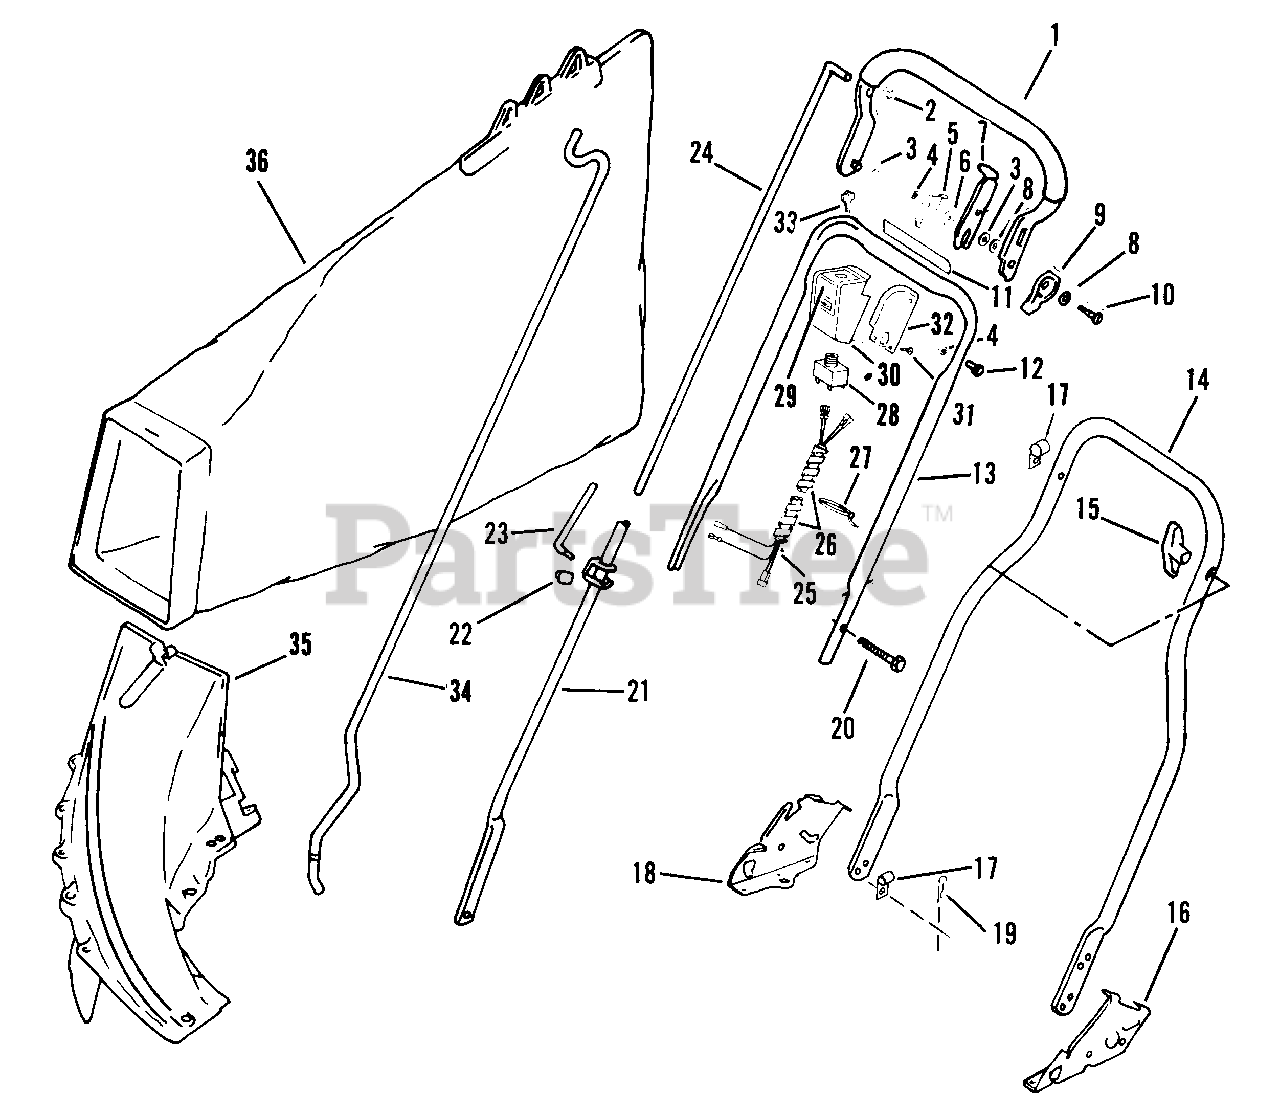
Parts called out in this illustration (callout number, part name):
1	Handle & Grip Assembly
2	Nut
3	Washer
4	Nut-Lock
5	Stop-Handle
6	Washer
7	Lever-Lockout
8	Washer
9	Guard-Lever
10	Bolt-Shoulder
11	Decal
12	Screw-Stop
13	Handle-Center
14	Handle Section-Bottom
15	Knob
16	Bracket-Handle L.H.
17	Clamp
18	Bracket-Handle R.H.
19	Hair Pin
20	Screw Bolt
21	Control Lever Assembly
22	Nut
23	Screw
24	Control Rod
25	Wire Harness Assembly Switch
26	Spiral Tubing
27	Cable Tie
28	Key Switch
29	Decal-Switch
30	Housing-Switch
31	Screw
32	Retaining Plate-Switch Housing
33	Keys-Switch
34	Rod-Grass Bag
35	Chute Assembly
36	Bag Assembly
